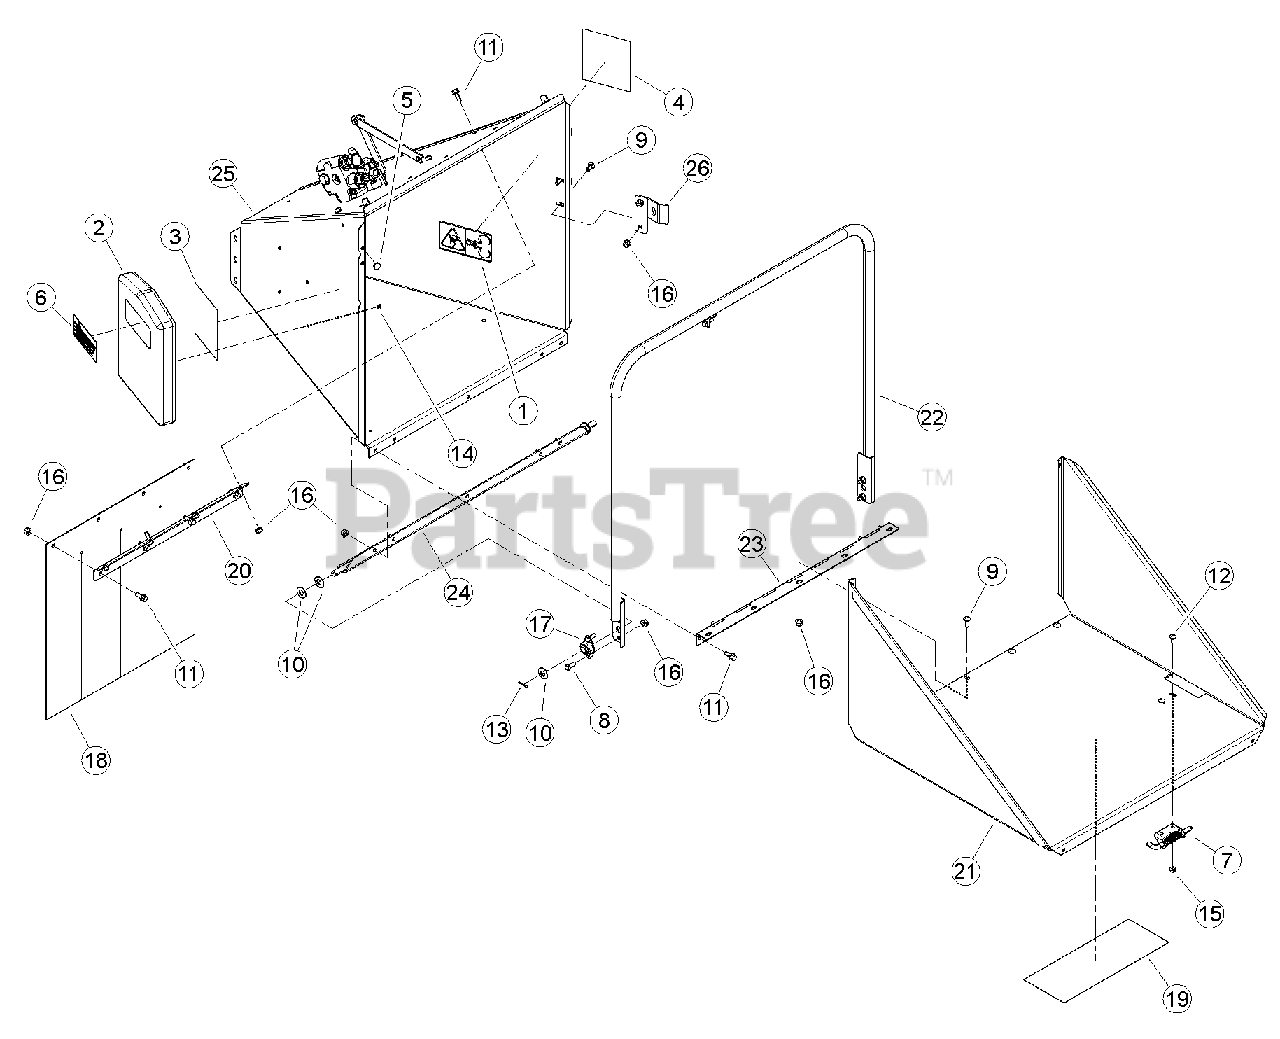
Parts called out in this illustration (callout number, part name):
1	DECAL, BLADE DANGER ISO
2	CONTAINER, INSTR. MANUAL
3	DECAL, FEED POSITION
4	DECAL, FEED POSITION
5	BUMPER, RUBBER
6	DECAL, MUTILINGUAL MANUAL
7	LATCH, RH HINGE
8	BOLT, 3/8 X 1 HEX HD GR5 ZP
9	BOLT, 3/8-16 X 1 GR5 CRG
10	WASHER, 5/8 SAE FLAT
11	BOLT, 3/8 X 1 FLANGE NC
12	BOLT, 5/16 X 3/4 GR5 CRG NC ZP
13	PIN, 1/8 X 1.00 ZP COTTER
14	RIVET, 1/4 X 1/2 DOME HD BLIND SS
15	NUT, 5/16-18 NYLOCK FLANGE
16	NUT, 3/8-16 NYLOCK FLANGE
17	BEARING, SIDE FLANGE MOUNT 5/8"
18	FLAP, 9 INCH CHUTE
19	DECAL, BEARCAT WEB
20	SUPPORT, 9 INCH CHIPPER FLAP
21	WELDMENT, CHUTE EXTENSION TRAY
22	WELDMENT, CONTROL ARM
23	HINGE, EXTENSION TRAY
24	WELDMENT, CONTROL PIVOT
25	WELDMENT, BIG CHIPPER CHUTE
26	PLATE, TRAY STOP (NO KNEE BAR)
